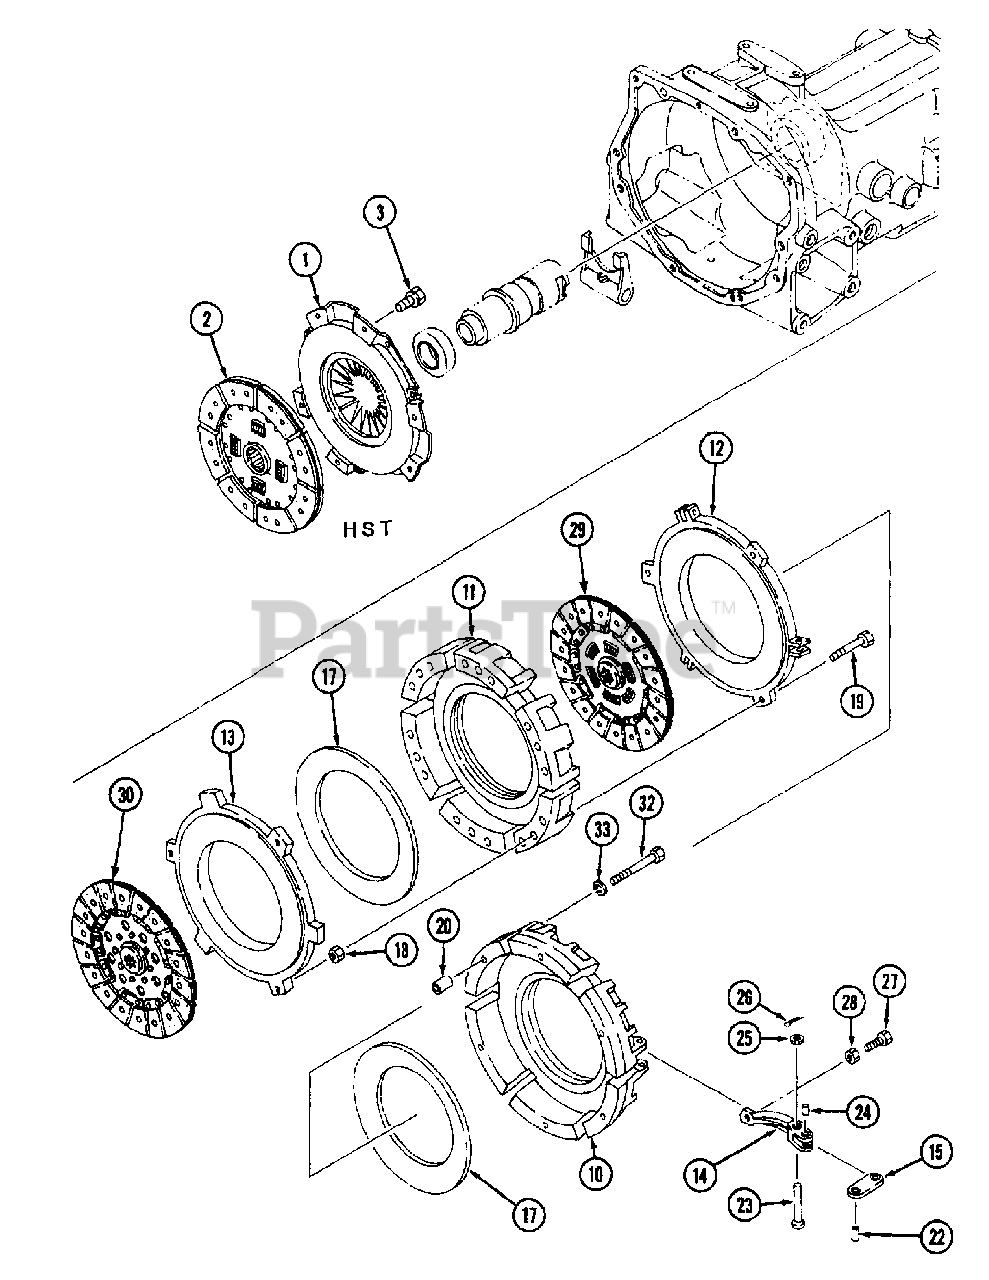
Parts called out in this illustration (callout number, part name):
1	Cover Ass'y.
2	Disc, Clutch
3	Bolt
10	Clutch, Cover
11	Clutch, Cover
12	Pressure Plate
13	Pressure Plate
14	Release Lever Sub Ass'y.
15	Release Rod Sub Ass'y.
17	Diaphragm Spring
18	Nut
19	Bolt
20	Knock Pin
22	Pin
23	Pin
24	Pin
25	Washer
26	Pin, Split
27	Adjust Bolt
28	Nut
29	Clutch Disc Ass'y.
30	Clutch Disc Ass'y.
32	Bolt
33	Washer
